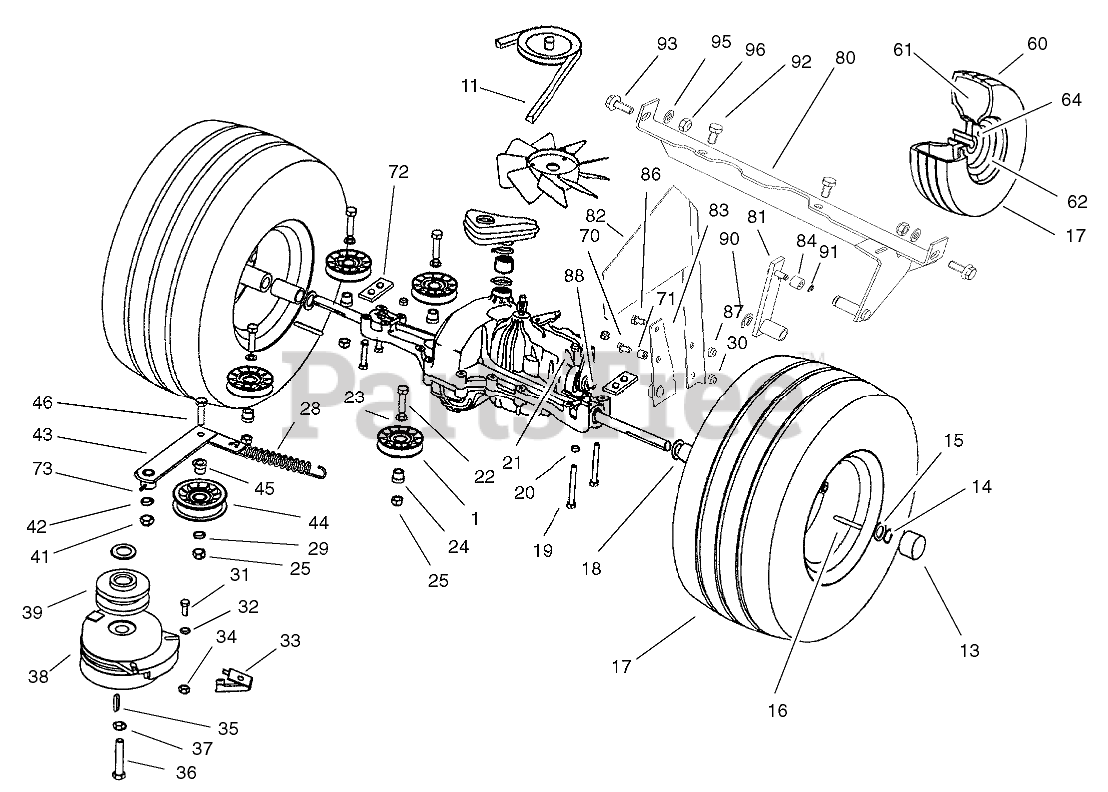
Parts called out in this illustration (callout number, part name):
1	PULLEY-IDLER
11	V-BELT-TRACTION
12	TRANSMISSION
13	CAP-HUB
14	CLIP-SPRING
15	WASHER
16	KEY-SQUARE
17	REAR TIRE ASM
18	SPACER-AXLE
19	SCREW-HH
20	WASHER-PLAIN
21	NUT-LOCK, NI
22	SCREW-HH
23	WASHER-FLAT
24	BUSHING-IDLER
25	NUT-LOCK, NI
28	SPRING
29	WASHER-FLAT
30	NUT-LOCK, NI
31	SCREW-HH
32	WASHER-PLAIN
33	RETAINER
34	NUT-LOCK, NI
35	KEY-SQUARE
36	SCREW-HH
37	WASHER-SPRING, BELLEVILLE
38	CLUTCH-ELECTRIC
39	PULLEY-ENGINE
41	NUT-LOCK, NI
42	WASHER-PLAIN
43	ARM-IDLER
44	PULLEY-IDLER
45	BUSHING-IDLER
46	SCREW-HH
60	TIRE-TURF SAVER 4 PLY
62	WHEEL ASM
64	NUT-WHEEL
70	SCREW-HH
71	SLEEVE
72	Plate-Reinforcing
73	FITTING-GREASE
80	Bar ASM
81	Arm-Switch
82	ARM-CONTROL, CRUISE
84	Roller
86	SCREW-HH
87	NUT-LOCK, NI
88	ARM-TRANSAXLE
90	Stirrup
91	STIRRUP
92	SCREW-THREAD FORMING
93	SCREW-HEX
95	WASHER-PLAIN
96	NUT-LOCK, NI
